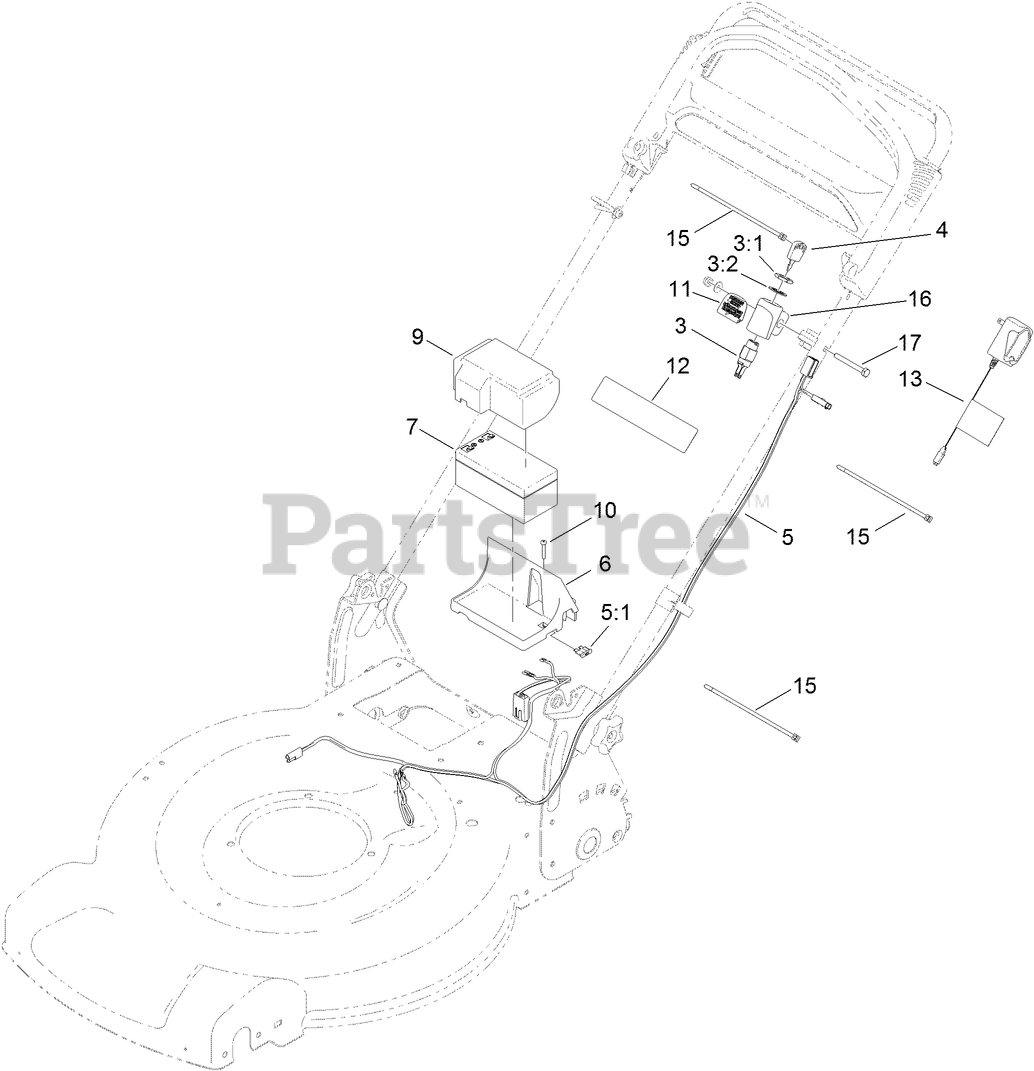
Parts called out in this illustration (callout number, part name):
3	STARTER SWITCH ASM
3:1	WASHER-LOCK
3:2	NUT-HH
5	HARNESS-WIRE, ES
5:1	FUSE-40 AMP
6	TRAY-BATTERY
7	BATTERY-WET
9	COVER-BATTERY
10	SCREW-PPH, PLASTITE
11	DECAL-ELECTRIC START
12	DECAL-WARNING
15	TIE-CABLE
16	MOUNT-SWITCH
17	SCREW-HH
